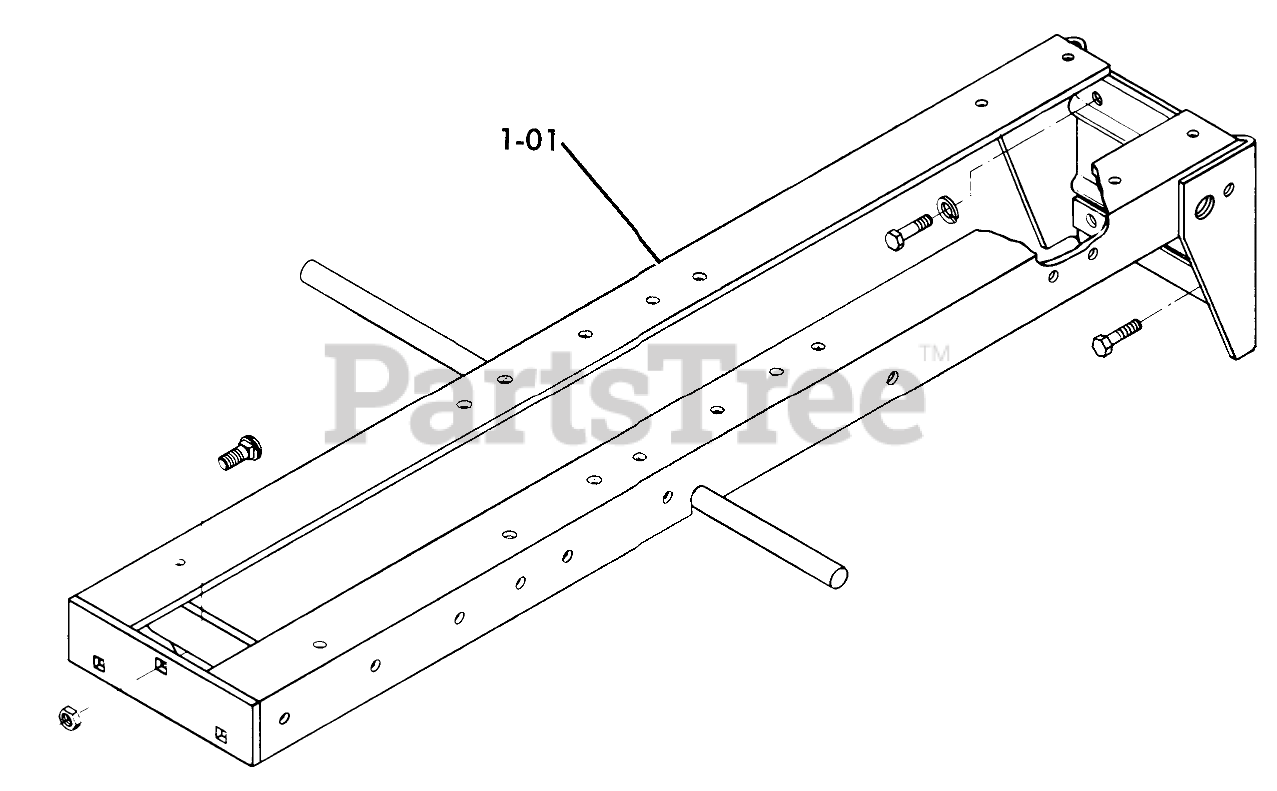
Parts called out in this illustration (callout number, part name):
1-01	Assy-Frame
1-01	Bolt
1-01	LOCKWASHER
1-01	Nut
